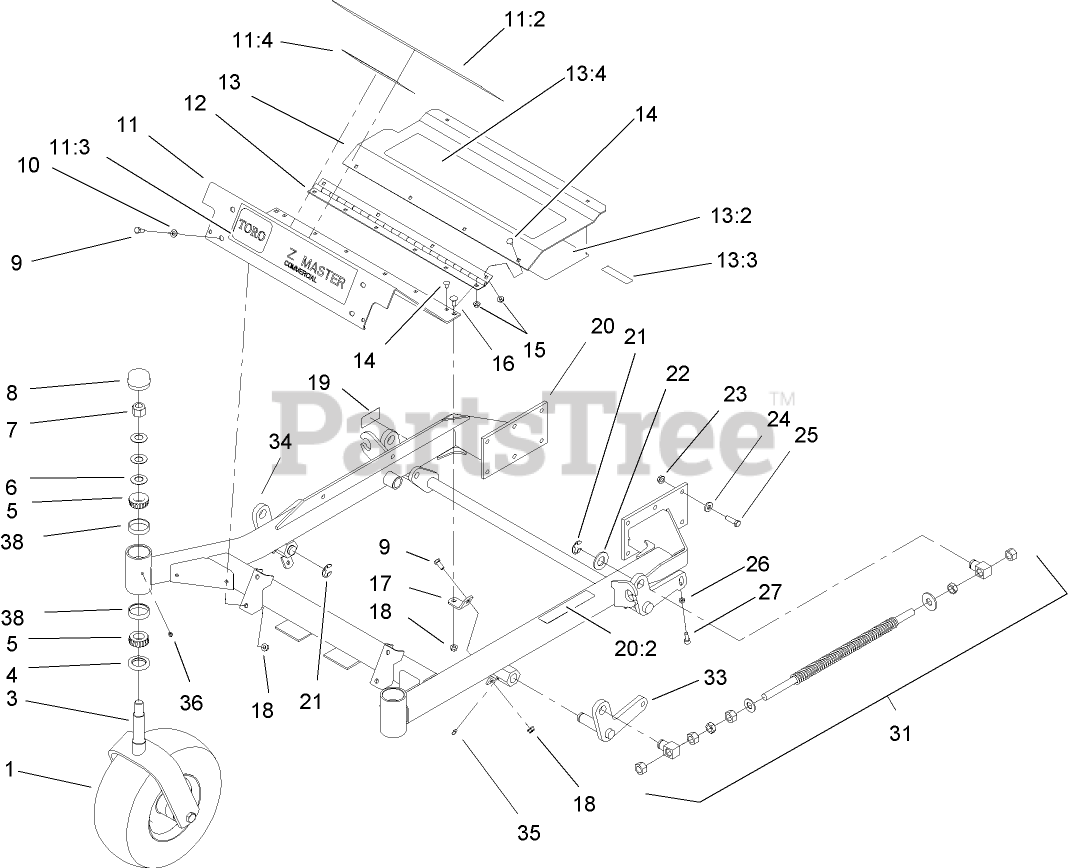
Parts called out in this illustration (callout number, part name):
1	CASTER WHEEL ASM
3	CASTER
4	SEAL-GREASE
5	BEARING-CONE, TAPERED
6	WASHER-BELLVILLE
7	NUT-LOCK, NI
8	CAP-GREASE
9	SCREW-HH
10	WASHER-PLAIN
11	FLOORPAN ASM
11:2	PAD-ANTISKID
11:4	DECAL-WARNING
12	HINGE-FLOORPAN
13	FOOTREST ASM
13:2	DECAL-SERVICE
13:3	DECAL-COVER, MISSING
13:4	PAD-ANTISKID
14	SCREW-CARR
15	NUT-HF
16	BOLT-CARR
17	BRACKET-FLOORPAN
18	NUT-HF
19	DECAL-STD, SAFETY
20	FRONT FRAME ASM
20:2	DECAL-WARNING
21	RING-RETAINING, EXT
22	WASHER-FLAT
23	NUT-HHF, WHIZ
24	WASHER-BELLEVILLE
25	SCREW-HH
26	NUT-JAM
27	SCREW-HSH
31	Front Spring ASM
33	LH FRONT DECK LIFT ASM
34	RH FRONT DECK LIFT ASM
35	FITTING-GREASE
38	BEARING-CUP, TAPERED
